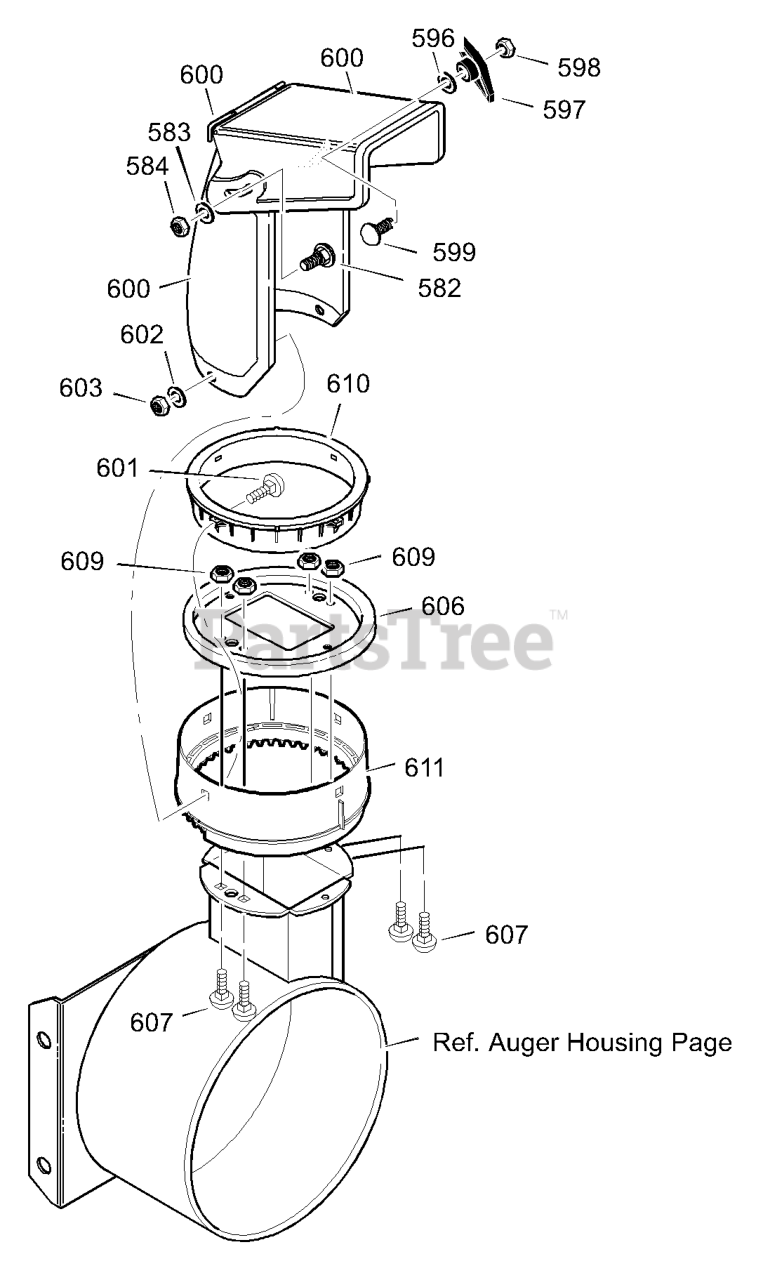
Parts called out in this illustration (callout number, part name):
582	SCREW, 5/16-18 x 1.00
583	WASHER, FLAT
584	NUT, 5/16-18
596	WASHER
597	KNOB, T 3.00
598	NUT, 5/16-18
599	BOLT, 5/16-18X1..00
600	CHUTE ASSEMBLY
601	BOLT, 5/16-18
602	WASHER, FLAT
603	NUT, 5/16-18
606	CHUTE COLLAR
607	SCREW, 1/4-20 X 0.75
609	NUT, 1/4-20 HEX NYLOCK
610	RETAINER RING INNER
611	RETAINER RING OUTER
